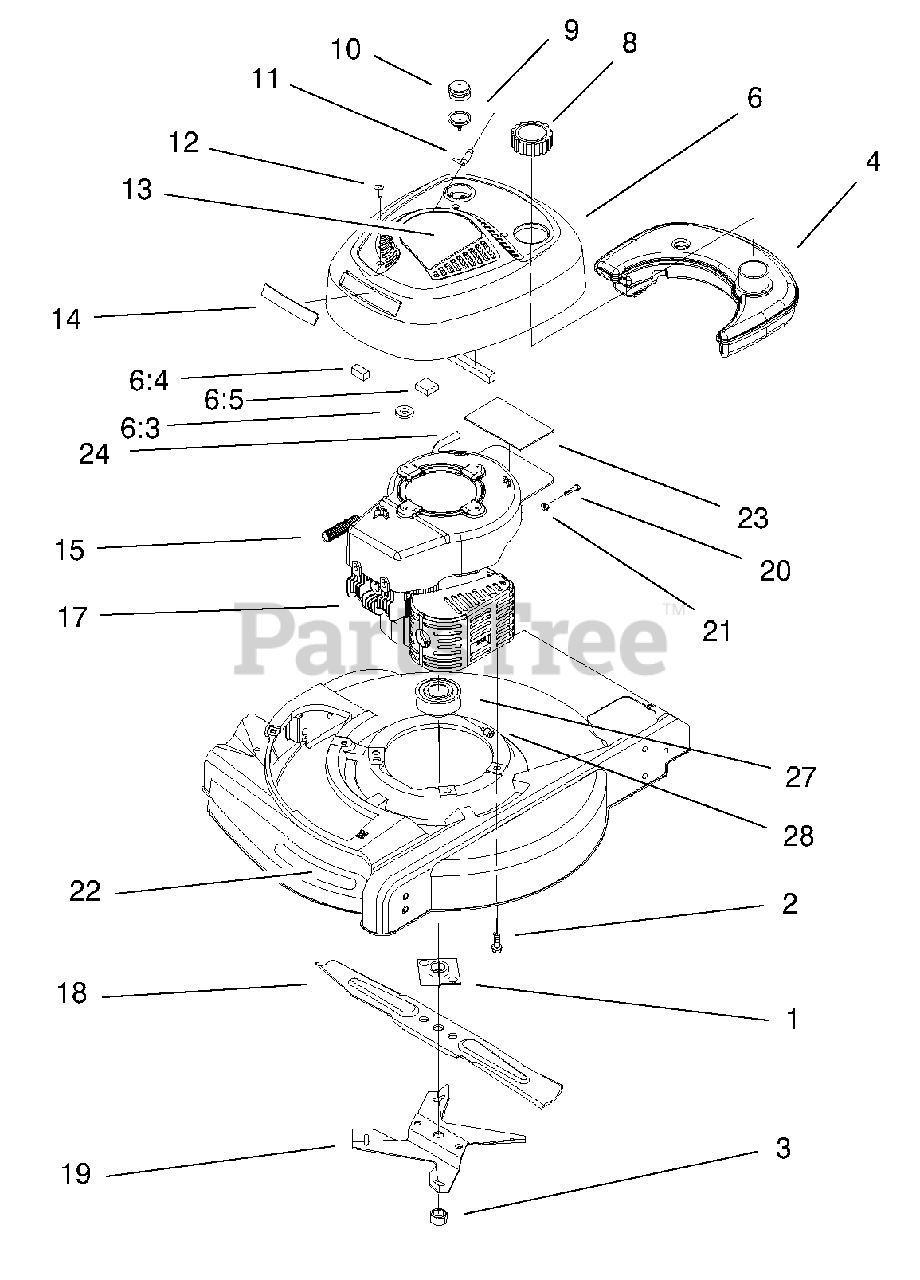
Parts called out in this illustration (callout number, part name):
1	Plate & Collar ASM
2	Screw-HH
3	Nut-Blade
6	ASM-Shroud/Recoil Cover
6:3	Nut-Push
6:4	Strip-Foam
6:5	Strip-Foam
8	Assembly-Cap, Fuel/Oil
9	Bulb-Primer
10	Body-Primer
11	Stop-Rope
12	Screw-Pan Sems
13	Decal-Recoil
14	Applique-Shroud
15	Spring-Compression
17	Engine Ay Sp E Silver
18	Blade-21" Whirl
19	Fan-Mulching
20	Screw-Sems
21	Nut-Hex S
22	Decal-Deck
23	Pad-Foam
24	Line-Gas
28	Screw-Set
